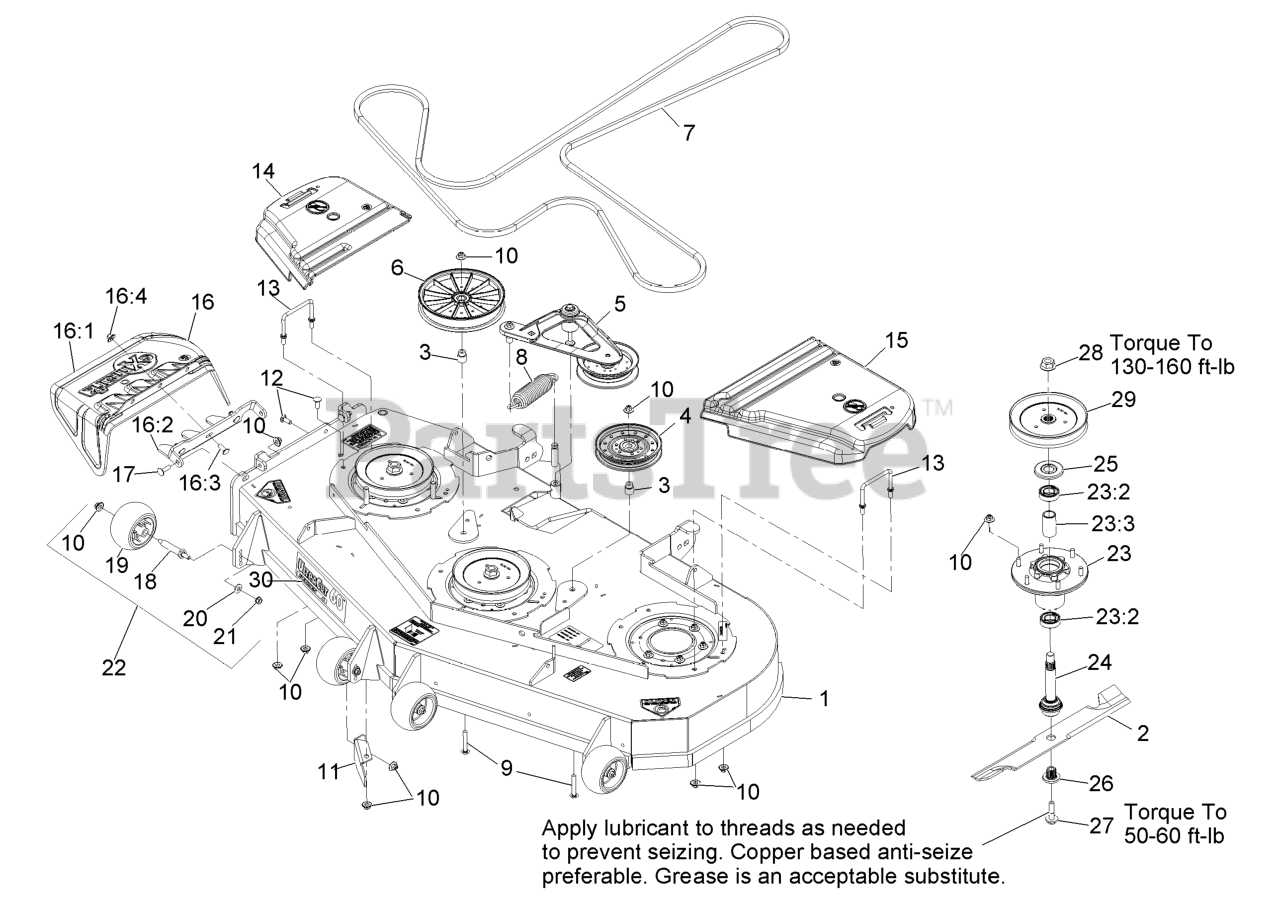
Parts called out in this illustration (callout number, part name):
1	DECK ASM,W/DECALS 60
3	BUSHING-IDLER
5	DECK IDLER ASM
6	PULLEY,IDLER 8"FLAT
7	BELT,V-5V-198.75
9	SCREW-CARR
10	Nut-Nyloc 3/8-16 Flg
11	BAFFLE,DISCHARGE 52/60
12	SCREW-CARR
13	WIREFORM-COVER
14	COVER-BELT, RH
15	COVER-BELT, LH
16	ASM,DISCHARGE CHUTE
16:1	CHUTE,DISCHARGE
16:2	BRACKET,DISCHARGE CHUTE
16:3	SCREW-CARR
16:4	Nut-Nyloc 3/8-16 Flg
17	Bolt-Carriage 3/8-16 X 1 1/4
19	ROLLER-SCALP, ANTI
20	WASHER-BELLEVILLE
21	NUT-HHF, WHIZ
23	ASM-CUTTER HSG WITH BEARINGS
23:2	BEARING-BALL
23:3	SPACER-BEARING
24	ASM-SPINDLE AND SEAL
25	GUARD,BEARING TOP .989
26	BUSHING,SPLINED
27	SCREW,SEMS 1/2-20 X 2.19
28	NUT-FLANGE
29	SHEAVE,BLADE DRIVE 7.25
30	DECAL,ULTRACUT 60 SERIES
